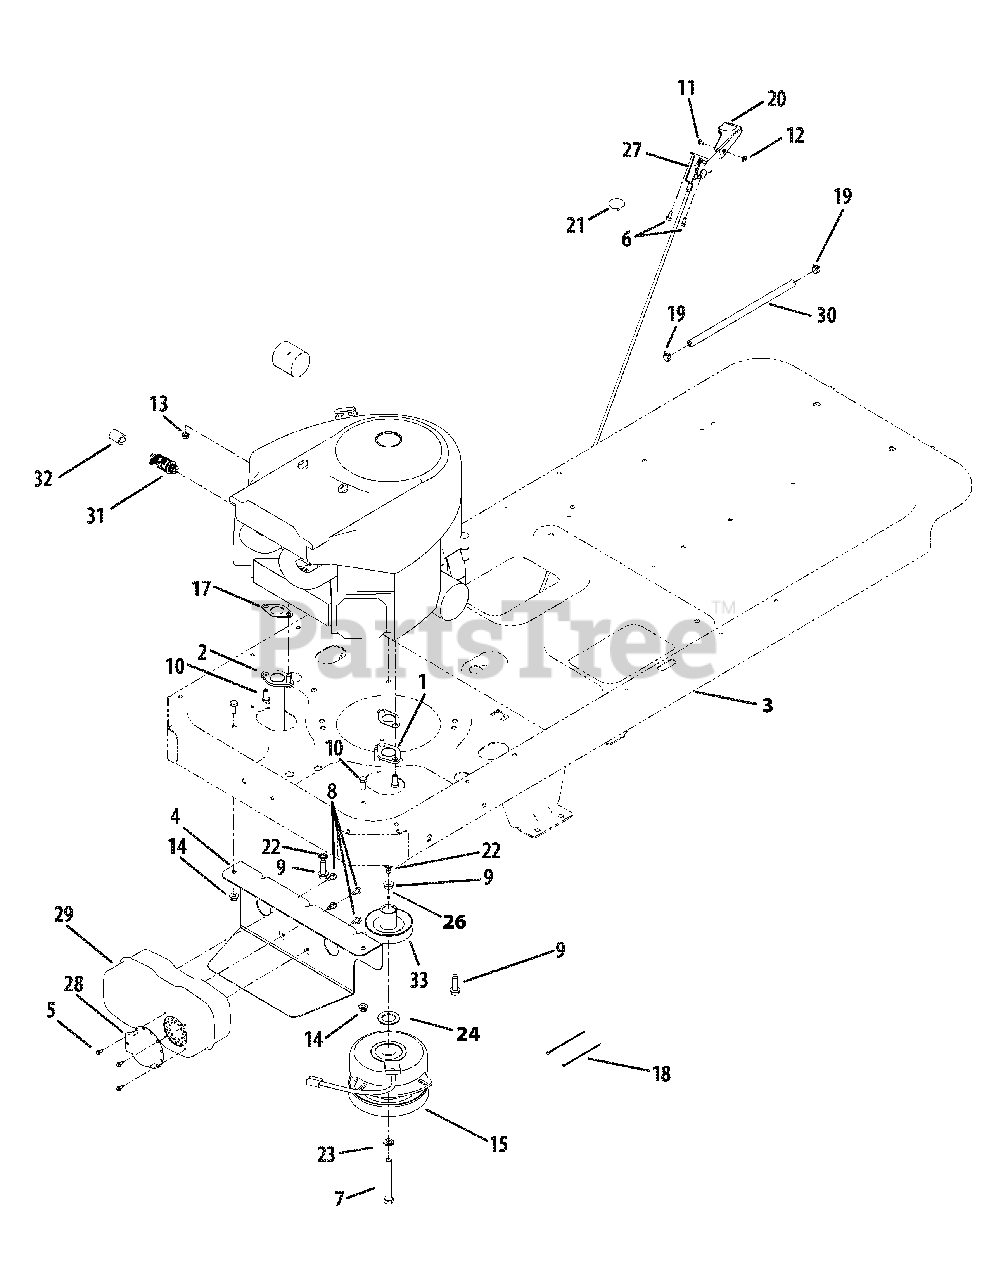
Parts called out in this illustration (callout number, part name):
1	Exhaust Pipe RH
2	Exhaust Pipe LH
3	Frame Ass'y
4	Muffler Mtg. Bracket
5	Hex Wash HD AB S-Tapp Scr #8-.50
6	Screw, 1/4-14 x .625
7	Hex Cap Scr. 7/16-20 x 4.0
8	Hex Wash S-Tapp Scr 1/4-20 x .50
9	TT Screw 3/8-16 x 1.00
10	Hex Bolt 5/16-18 x .75" Lg. Gr. 5
11	Torx Screw, #8-32 x .375
12	Hex Nut #8-32, 0.375
13	Sems Hex Nut 1/4-20
14	Flange Locknut 5/16-18 Gr. F, Nylon
15	Clutch Assembly, Electric PTO
17	Exhaust Gasket
20	Throttle Control Knob
22	L-Washer 3/8" ID (Ext. Tooth)
23	Lockwasher 7/16 ID
24	Flat Washer 1.031 x 1.620 x .095
26	Grease
27	Throttle/Choke Cable 41.5" Lg.
28	Muffler Deflector
29	Muffler
30	Fuel Hose; Low Permeation, 8" Lg.
32	Extension Hose
33	Engine Pulley, Electric PTO
